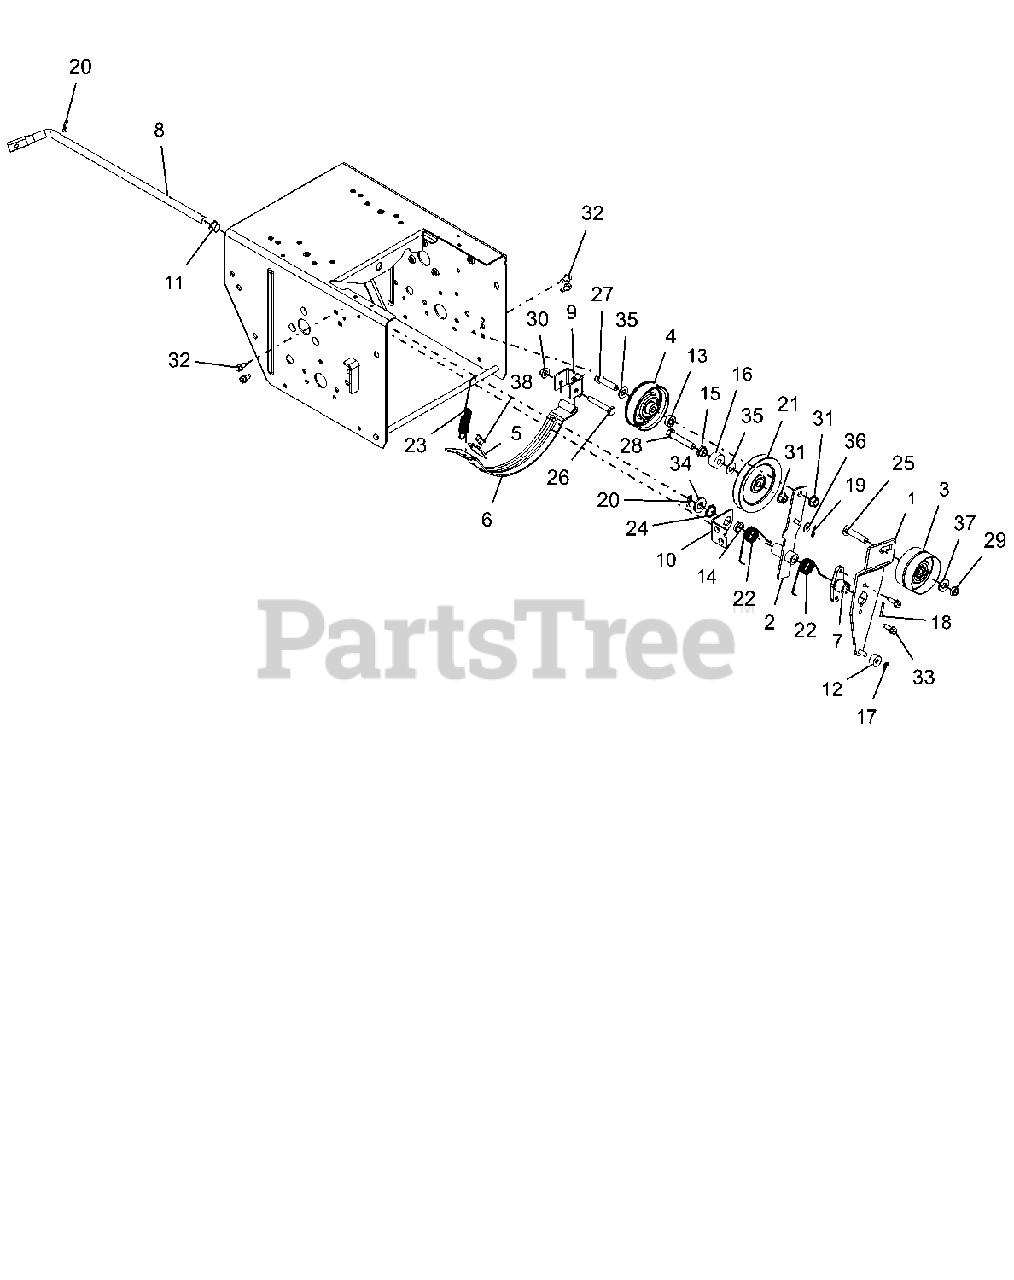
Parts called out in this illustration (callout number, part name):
1	ARM, IDLER-ATTACHMENT
2	ARM, TRACTION CLUTCH
3	IDLER, FLAT-2.75 OD X .375 ID
4	IDLER, FLAT - 3.05" X .75"
5	PAD, BRAKE
6	ARM, BRAKE-ATTACHMENT
7	HUB, BRAKE ARM
8	ARM, ATTACHMENT
9	PIVOT, BRAKE
10	BRACKET, SUPPORT
11	BUSHING, POLYLINER-.50 SPLIT
12	BSHG,SLV .265 X .625 X .375
13	SPCR, BRG .315X.500X.358X.281
14	BSHG,FLANGE .500X.625X.270X.75
15	BSHG, FLANGE .391X.56X.313X.75
16	BSHG,POCKET .391X.570X1.0X.450
17	RG-RTNG-EXT .250X.010
18	PIN-ROLL .125X1.00
19	PIN-HAIR INT .06X.18X.77
20	CLIP, SPRING
21	SHV, .38"ID X 4.00"OD V-IDLER
22	SG-TORS .067X.88
23	SG-TENS .056X.60X4.40
24	WAVE SPRING .600X.875X.25FH
25	@BLT-RHDSSQNK .38-16X1.75 G5YZ
26	@BLT-HEX .31-18X2.00 GR5 YWZC
27	@BLT-HEX .38-16X1.50 GR5 YWZC
28	@BLT-HEX .38-16X2.00 GR5 YWZC
29	@NUT-LK-CTR-JAM .375-16 YWZC
30	@NUT-LK-TOP-FLG .31-18 YWZC
31	@NUT-LK-TOP-FLG .38-16 YWZC
32	SCR-TAP .25-20X.50 HWH TR YWZ
33	SCR-TAP-PM .25-20X.75 TR YWZ
34	@WSHR-FL-STL.531X1.06X.095YWZC
35	@WSHR-FL-STL.406X.812X.065 YWZ
36	@WSHR-FL-STL.281X.62X.065 YWZC
37	@WSHR-FL-STL.38X.875X.083 YWZC
38	RVT-POP .187 YZ
